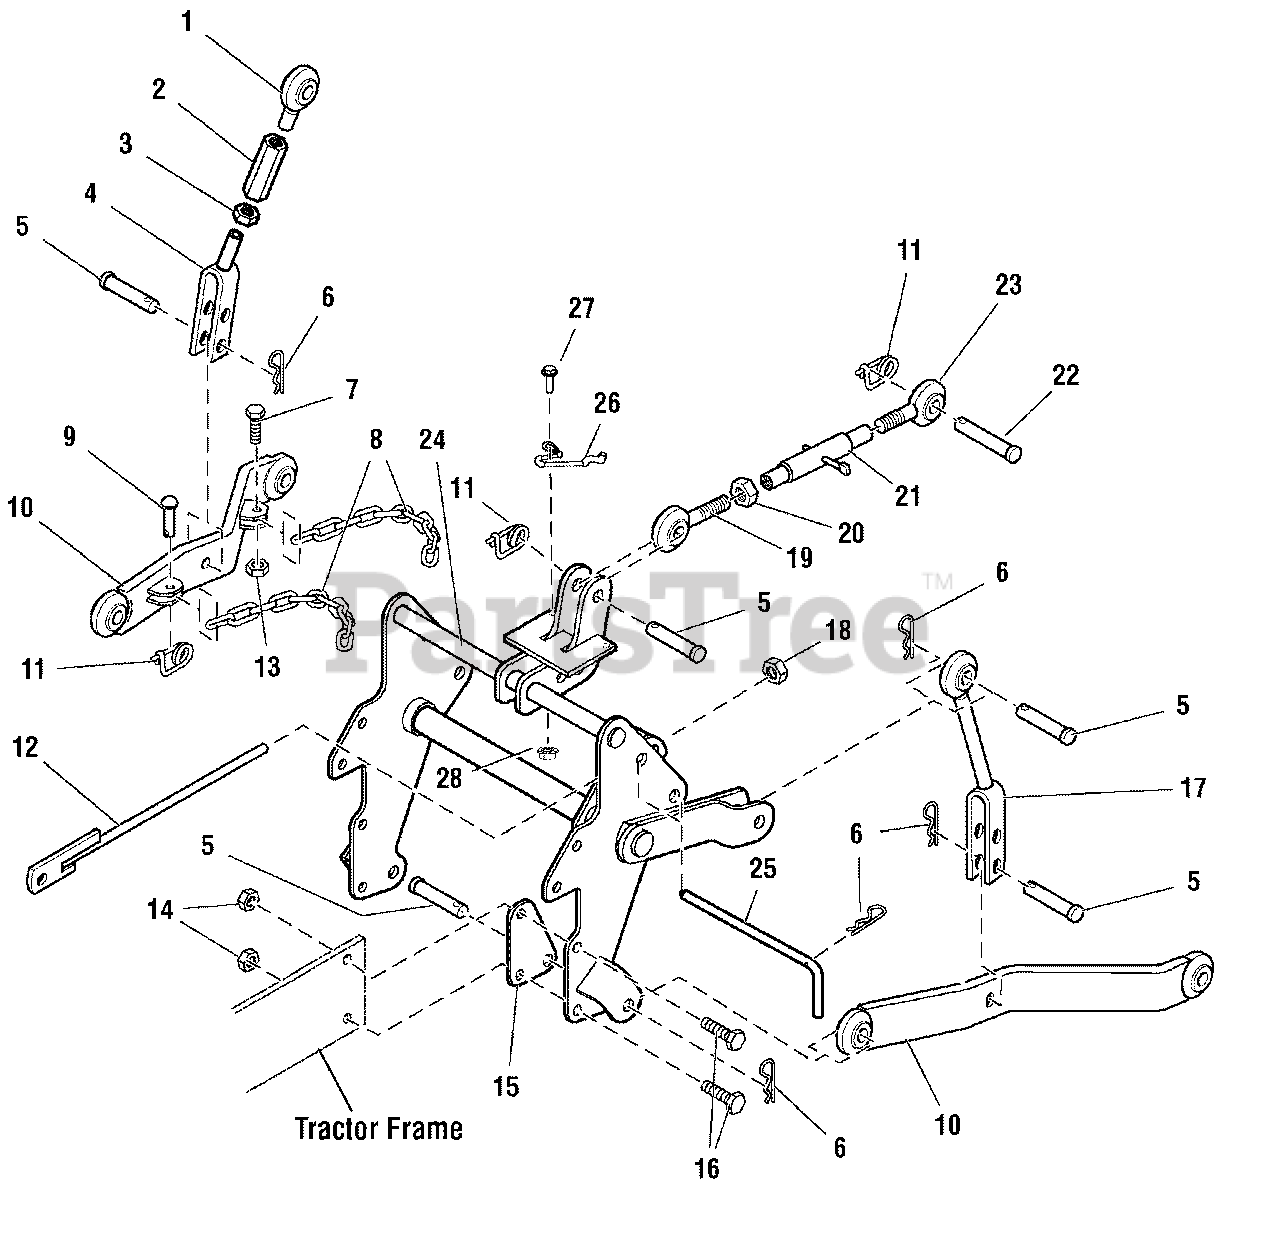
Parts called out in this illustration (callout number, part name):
1	BALL JOINT & STUD ASSEMBLY, R.H., Upper
2	TURNBUCKLE, 5/8-18 x 2-1/2
3	NUT, Hex, Jam, 5/8-18
4	CLEVIS ASSEMBLY
5	PIN, Clevis, 5/8 x 2-1/2
6	CLIP, Hair Pin
7	CAPSCREW, Hex Head, 3/8-16 x 1-1/2
8	CHAIN, 16 Link
9	PIN, Round Head, 3/4 x 1-1/2
10	LINK & BALL JOINT ASSEMBLY
11	PIN, Spring
12	ROD ASSEMBLY, Lift
13	LOCKNUT, Hex, Nylock, 3/8-16
14	LOCKNUT, Hex, 1/2-13
15	SUPPORT, Inner, Pin
16	CAPSCREW, Hex, 1/2-13 x 1-1/2
17	CLEVIS ASSEMBLY, Fixed
18	NUT, Hex Top Lock, 1/2-13, Yellow
19	STUD & BALL JOINT ASSEMBLY, R.H.
20	NUT, Jam, 3/4-10
21	TUBE & PIN ASSEMBLY, Upper
22	PIN, Clevis, Rear
23	BALL JOINT & STUD ASSEMBLY
24	HITCH ASSEMBLY
25	ROD, Hitch
26	CLAMP, Upper Link .162 Diameter, Stainless, Black
27	Screw, Hex Lock Flange, 5/16-18 x 1
28	NUT, Hex, Conical Washer, 5/16-18
